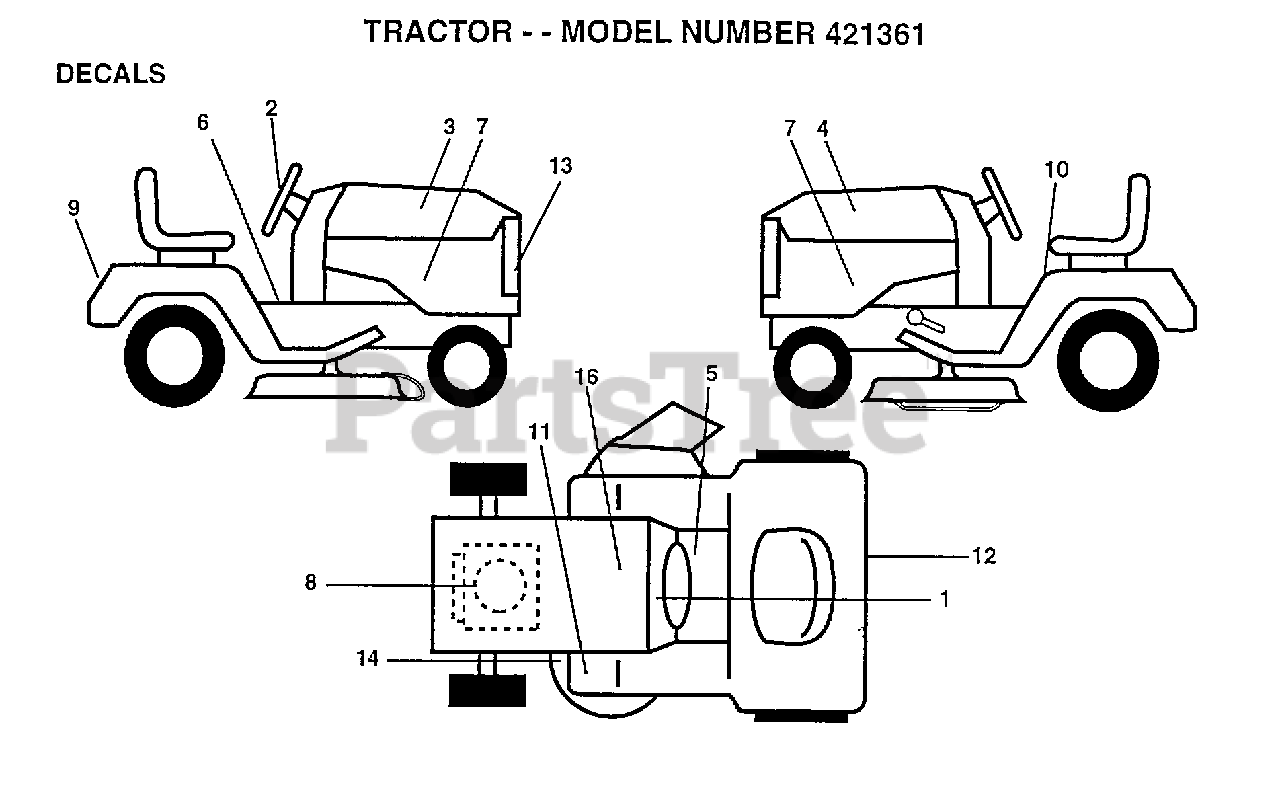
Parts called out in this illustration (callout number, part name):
1	DECAL.DASH.INST.
2	DECAL.INS.WHL.STG
4	DECAL HOOD LH
5	DECAL BRAK PARK
6	DECAL SADLE HYDRO
7	DECAL PANEL SIDE
8	DECAL KOHLER 20 OHP DMD
10	DECAL
12	DECAL D-BAR CNTRL
13	DECAL.GRILL.YARDP
14	"DECAL.V.BELT.44"""
16	DECAL.BTRY.DANGER
